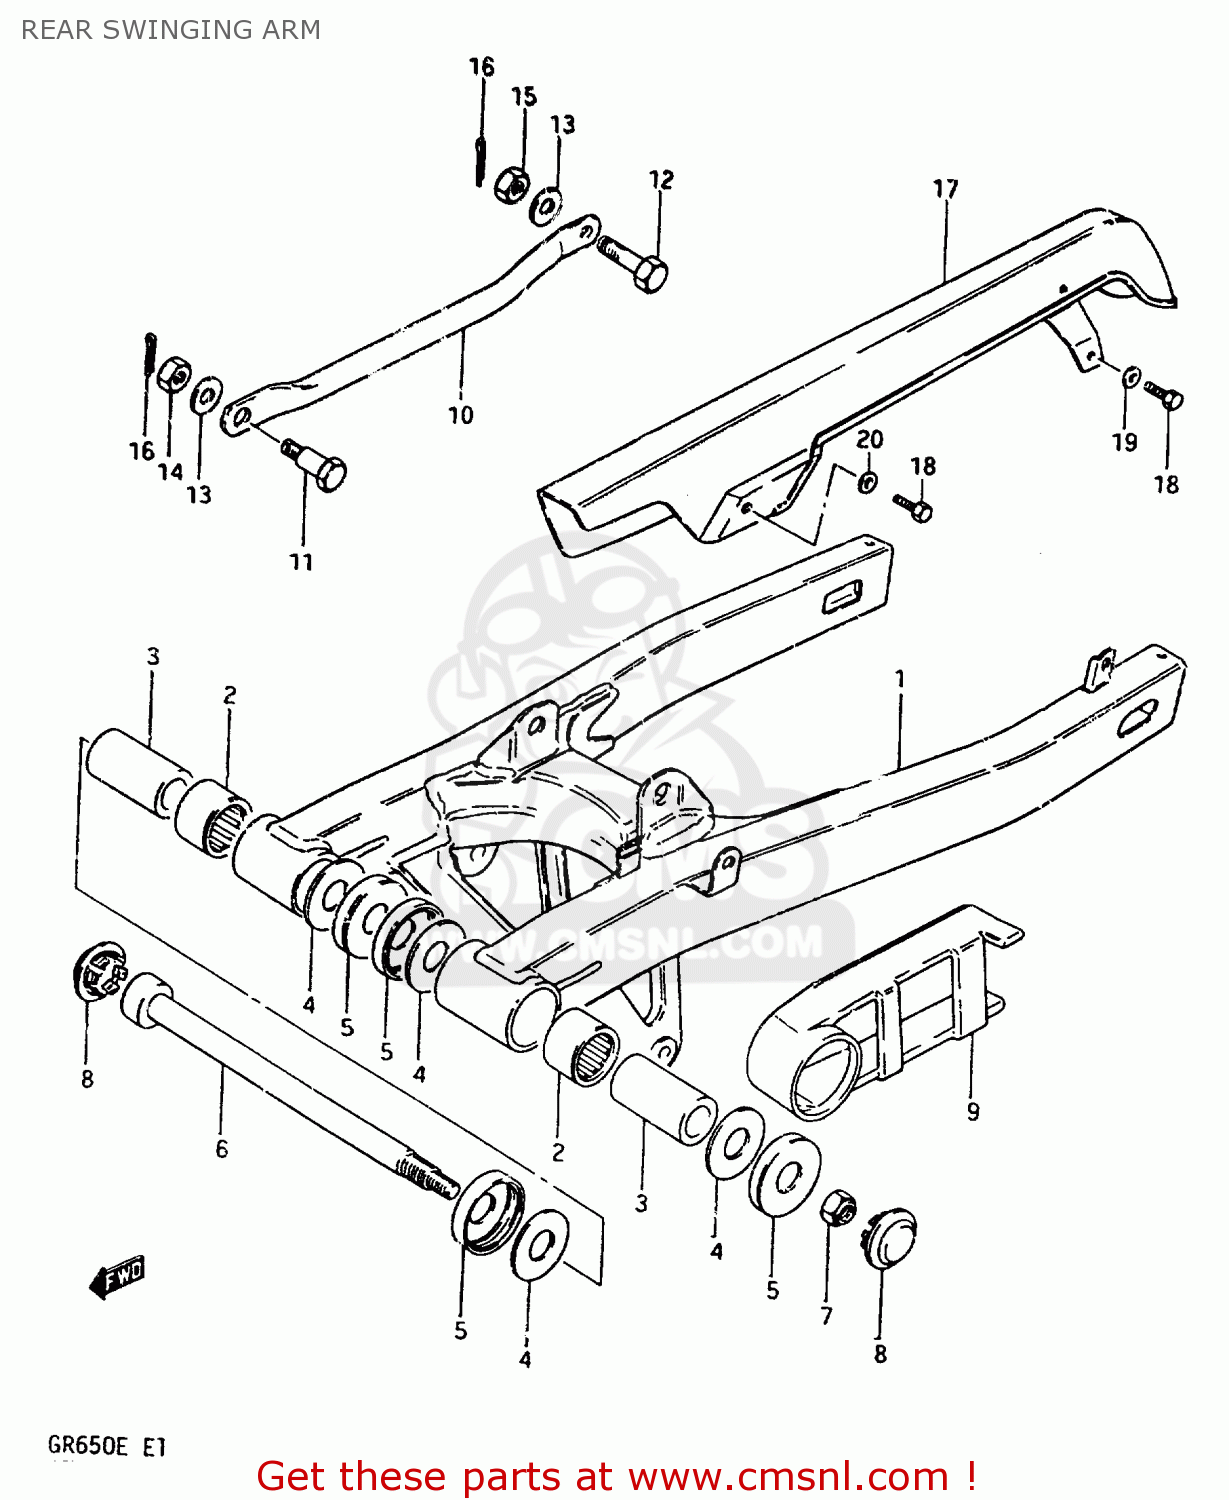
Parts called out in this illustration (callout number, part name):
1	SWING ARM ASSEMBLY,REAR
2	BEARING(25X33X30)
3	SPACER,RR SWGARM PIVOT
4	WASHER
5	COVER,RR SWGARM DUST SEAL
6	SHAFT,REAR SWING ARM
7	NUT 12MM
8	CAP,REAR SWING ARM PIVOT
9	BUFFER,DEFENSE
10	LINK,REAR TORQUE
11	BOLT(10X24.5)
12	BOLT(10X31)
13	LOCK WASHER
14	NUT
15	NUT
16	PIN 20X20
17	CASE,CHAIN
18	BOLT 6X8
19	WASHER
20	WASHER
